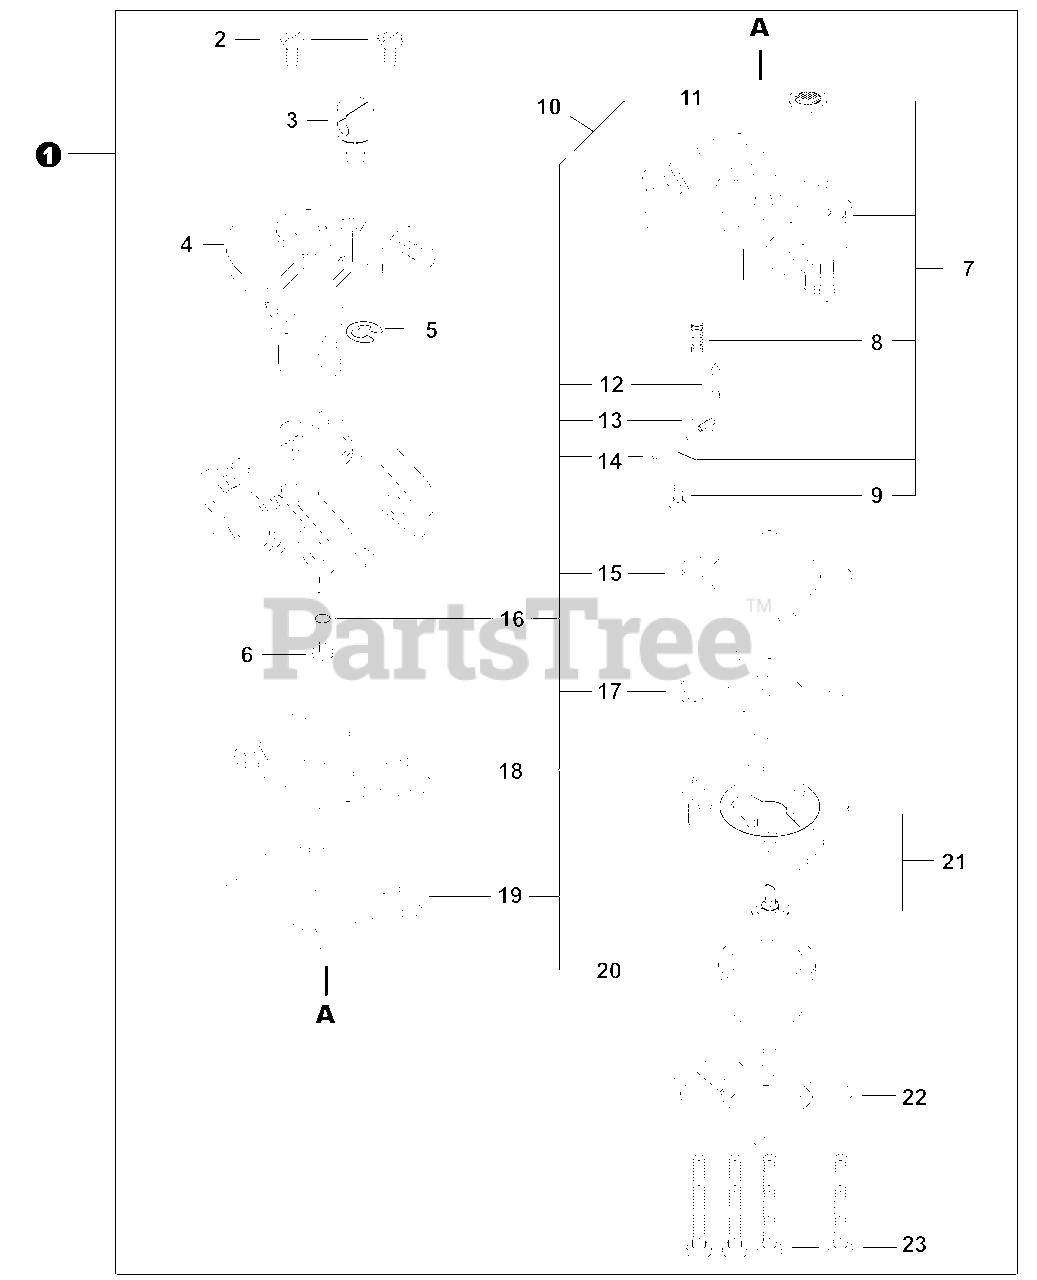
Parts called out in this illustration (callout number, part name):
1	CARBURETOR - WYL-170
2	SCREW, THROTTLE COLLAR
4	VALVE ASSY, THROTTLE
6	JET, MAIN #37
7	BODY ASSY, PUMP
8	SPRING, METERING LEVER
10	REPAIR KIT, CARBURETOR
11	SCREEN, FUEL INLET
12	VALVE, INLET NEEDLE
13	LEVER, METERING
14	PIN, METERING LEVER
15	GASKET, METERING DIAPHRAGM
17	DIAPHRAGM, METERING
18	GASKET, PUMP
19	DIAPHRAGM, PUMP
20	BULB, PURGE
21	BODY ASSY, PURGE
22	RETAINER, PURGE BULB
